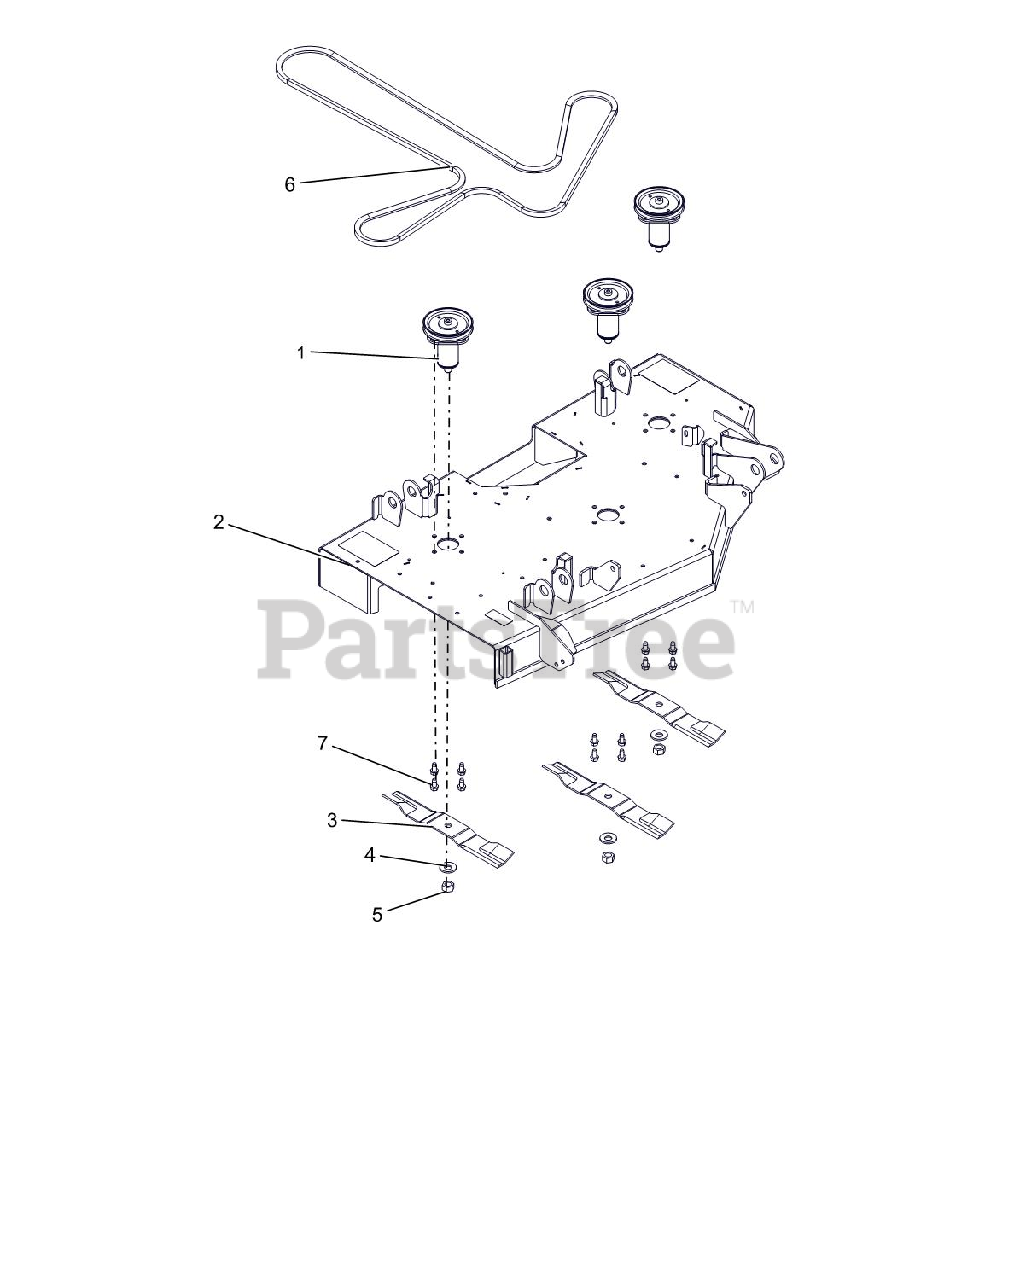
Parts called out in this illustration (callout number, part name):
1	KIT, DECK SPINDLE ASM-IKON-ZTX
2	KIT, 42" ARIENS DECK W/DECALS
3	BLADE, MOWER 15.00"
4	WSHR-BLVL .669X1.535X.138
5	NUT-HEX .62-18 YWZC
6	V-BELT, 4L-WRAPPED
7	@SCR-TAP .38-16X.75 HWH TR YWZ
